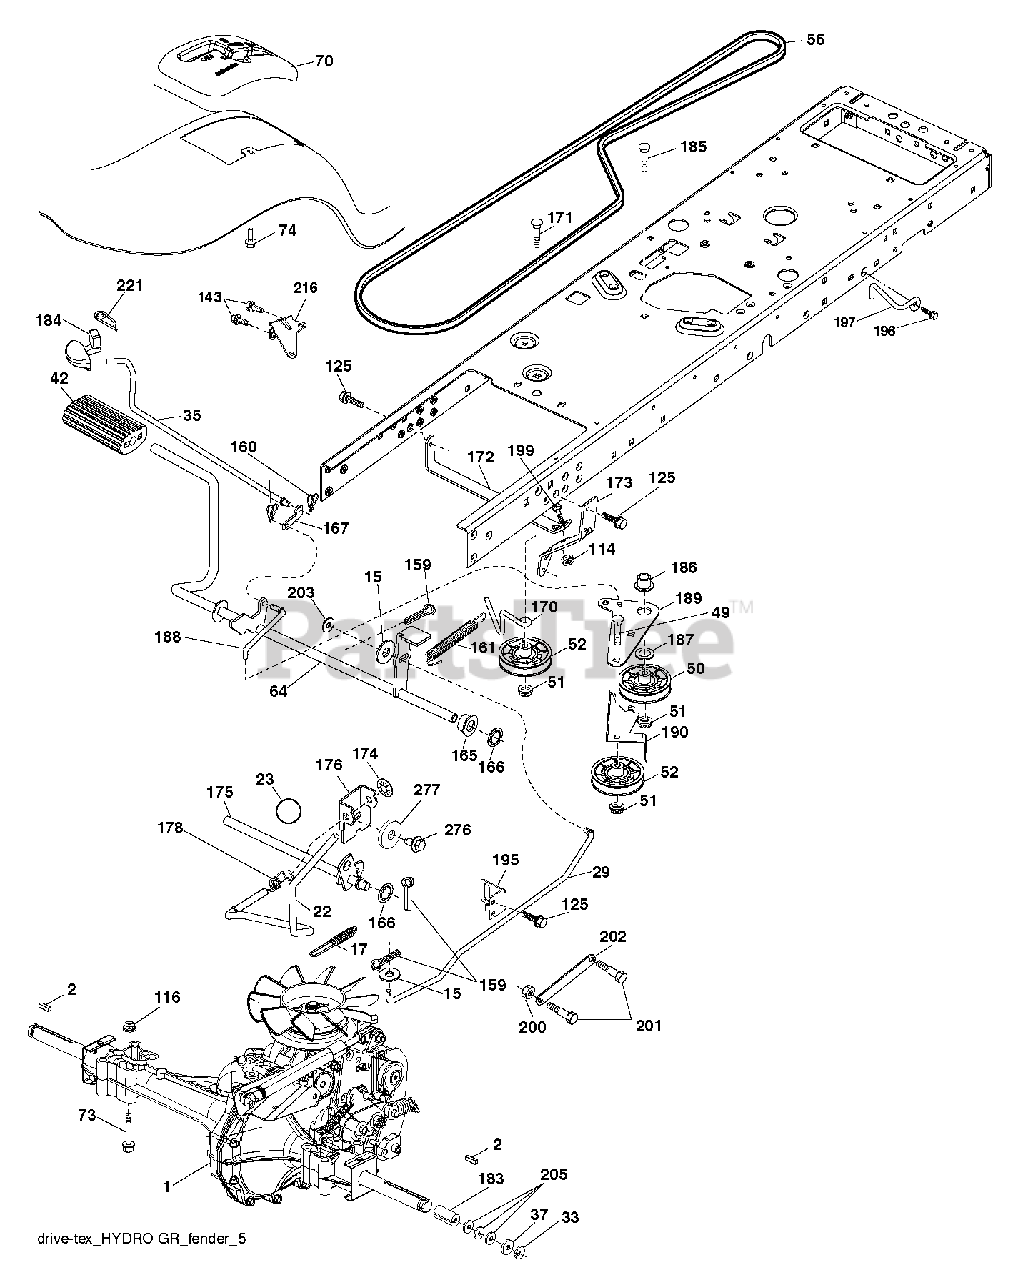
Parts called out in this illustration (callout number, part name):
2	SQUARE KEY
17	SPRING.BRAKE.HG3000/3500
22	ROD.SHIFT.FENDER.STGT.
23	PISTOL KNOB
29	ROD.BRAKE.HG-0510
33	E-RING LT
35	ROD.BRKAE.PARKING.STEALTH
42	PEDAL COVER T
49	BOLT
50	IDLER.FLAT.910.OFFSET
51	NUT LOCK FLG 3/8-16 UNC
52	IDLER.V-GROOVE.910.OFFSET
64	SHAFT.ASM.PEDAL.BRAKE.
73	BOLT HEX 5/16-18 GR 5
74	SCREW.HI-LO.CONSOLE
114	NUT.71038.31-18.HEX.NYLOCK
116	NUT LOCK HEX FLANGE 5/16-18
125	SCREW
159	COTTER PIN
160	RETAINER CLIP
161	SPRING, RETURN LT
165	BUSHING.SHAFT.BRAKE.HAND
166	NUT.PUSH.625.2006
167	LATCH.BRAKE.SPRING
170	KEEPER.V-IDLER.CENTER.
171	BOLT
172	STRAP.TRQ.LH.FS.HG0510
173	STRAP TORQUE RH
174	NUT.PUSH.500.2006
175	SHAFT.ASM.SHFT.HG0510/
176	ARM.CLEVIS.ROD.SHIFT
178	SPRING.SHIFT.GT2006
183	SPACER AXLE
184	HANDLE.PRKG.BRAKE.STLTH.TX.RED
186	SPACER.RETAINER
187	WASHER 12/32X2X10GA
188	LINK.CLUTCH.GROUND.DRIVE
189	BELLCRANK.GROUND.DRIVE.TEX.
190	KEEPER.BELLCRANK.DRIVE
195	BRKT.ROD.BRAKE.18/20/2
197	LINK.CLUTCH.ANIT-ROTAT
199	BOLT
200	NUT.CENTERLOCK.5/16-
201	BOLT SHOULDER 5/16-18 UNC
203	WASHER
216	BRACKET.PULLEY.IDLER.W/TEX
221	RETAINER.SPRING.CLIP.H
276	BOLT FIN HEX 7/16-14 X 1
277	WASHER SERRATED
